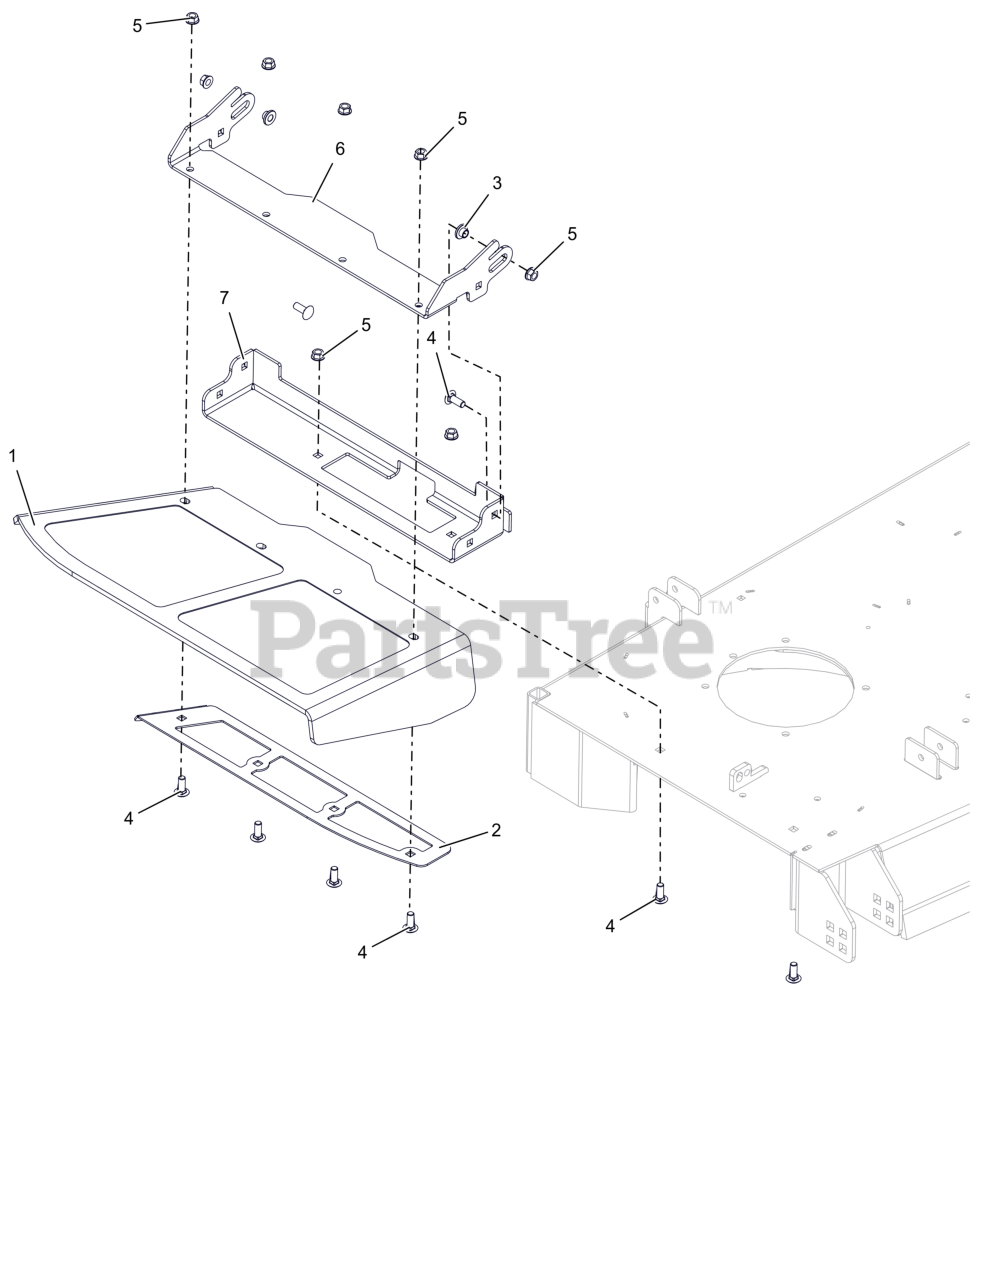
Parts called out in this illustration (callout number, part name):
1	CHUTE, FORMED RUBBER DISCHARGE-EXT
2	DISCHARGE CHUTE CLAMP PLT -RED
3	BSHG-FLG .385X.500X.875X.406
4	BLT,RHSSN .38-16X1.00 G5 ZCC
5	NUT-LK-CTR-FLG .375-16 GF ZCC
6	BRKT, CHUTE MTG (RED)
7	BASE, DISCHARGE CHUTE MTG (RED) W/ SAFETY DECALS
